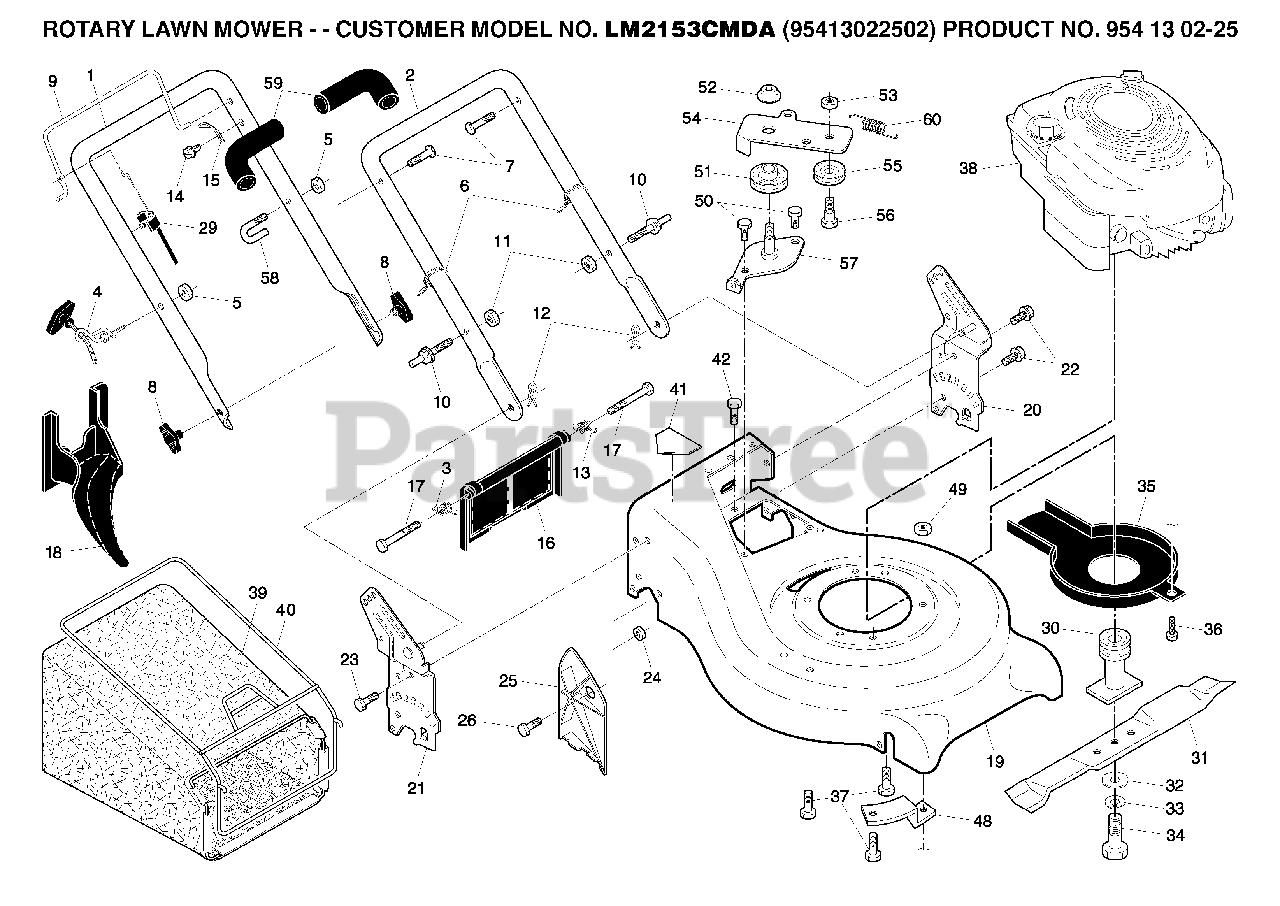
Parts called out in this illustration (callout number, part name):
2	HANDLE LOWER
3	SPRING, REAR DOOR, RH
4	ROPE, GUIDE
5	NUT
6	TIE GUIDE
7	BOLT, HANDLE 5/16-18X1.75
8	KNOB, DEFLECTOR
11	NUT.CENTERLOCK.5/16-
12	HAIRPIN COTTER
13	SPRING.LH.REAR.DOOR.21.RWGD
15	BRACKET UPSTOP
16	DOOR.REAR.PLASTIC.21.RWGD.BLAC
18	PLUG, MULCHER
20	BRKT.ASM HNDL
21	BRKT.ASM.HNDL
22	SELF-TAPPING SCREW 5/16-18X3/4
23	BOLT, HEX HEAD 5/16-18
24	NUT.71038.31-18.HEX.NYLOCK
25	CLIPPING DEFLECTOR
29	SNAP-ON.ZONE.CABLE.ASS
30	BLADE ADAPTOR / PULLEY
32	WASHER,HARDEN
33	LOCKWASHER
34	SCREW, HEX HD 3/8-24 X 1-3/8
35	DEBRIS SHEILD
36	SCREW.HEX.WSH
37	BOLT 3/8-16X1-1/8
40	GRASS CATCHER FRAME
41	DECAL.INTERNATIONL.CUTFINGER
48	BRACKET
51	PULLEY ASSY
52	HEX FLANGE LOCKNT
54	IDLER ARM
55	IDLER PULLEY
57	BRACKET ASSEMBLY
59	GRIP.HANDLE.FOAM.WIDE.(1 SIDE)
